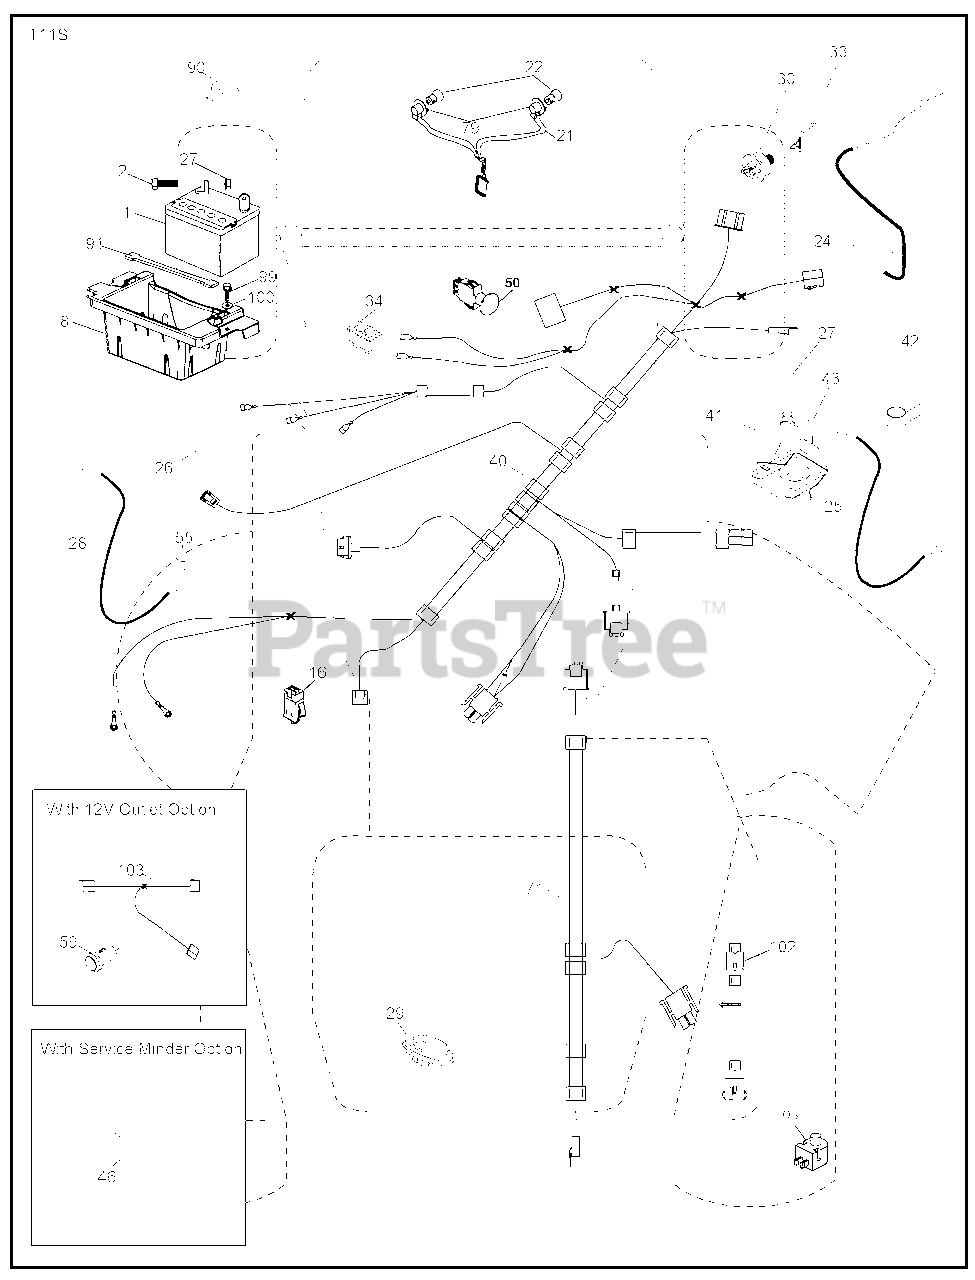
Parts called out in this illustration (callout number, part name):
1	Battery
2	Bolt Hex Head 1/4-20 x 3/4
8	Box Battery
16	Switch Interlock Push-In
21	Harness Socket Light w/4152J
22	Bulb Light
24	Cable Brty
25	Cable Starter
27	Nut Keps Hex 1/4-20 unc
28	Cable, Ground
29	Switch, Seat
30	Switch, Ign
34	Switch Light/Reset
40	Harness Ign. Dash
41	Screw Thd Cut 1/4-20 x 1/2
42	Cover, Terminal
43	Solenoid
46	Gauge Serviceminder Hrmtr
50	Switch PTO
55	Screw Thdrol 5/16-18 x 3/4 TYTT
71	Harness Ign.
79	Socket Asm. Bulb Twistlock
90	Cover Terminal
91	Strap Battery Mount Front
99	Screw Hexwsh Thdrol 1/4-20 x 3/4
100	Washer 9/32 x 7/8 x 16 Ga.
102	Harness Pigtail
105	Switch Reverse TT Pedal Control
